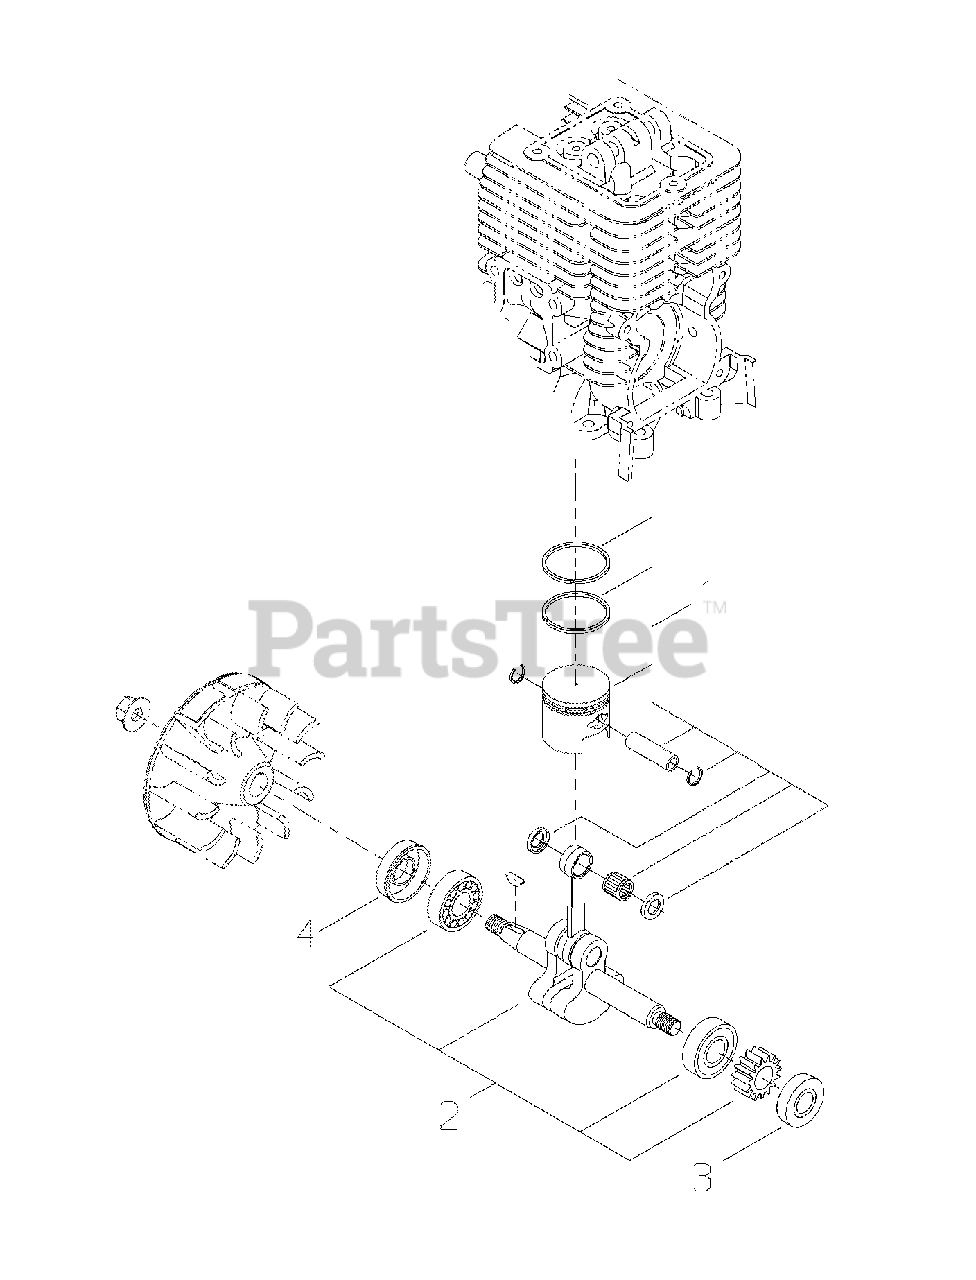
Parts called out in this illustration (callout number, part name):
1	PISTON KIT
2	CRANKSHAFT ASSY
3	SEAL, OIL - 12
4	SEAL, OIL
